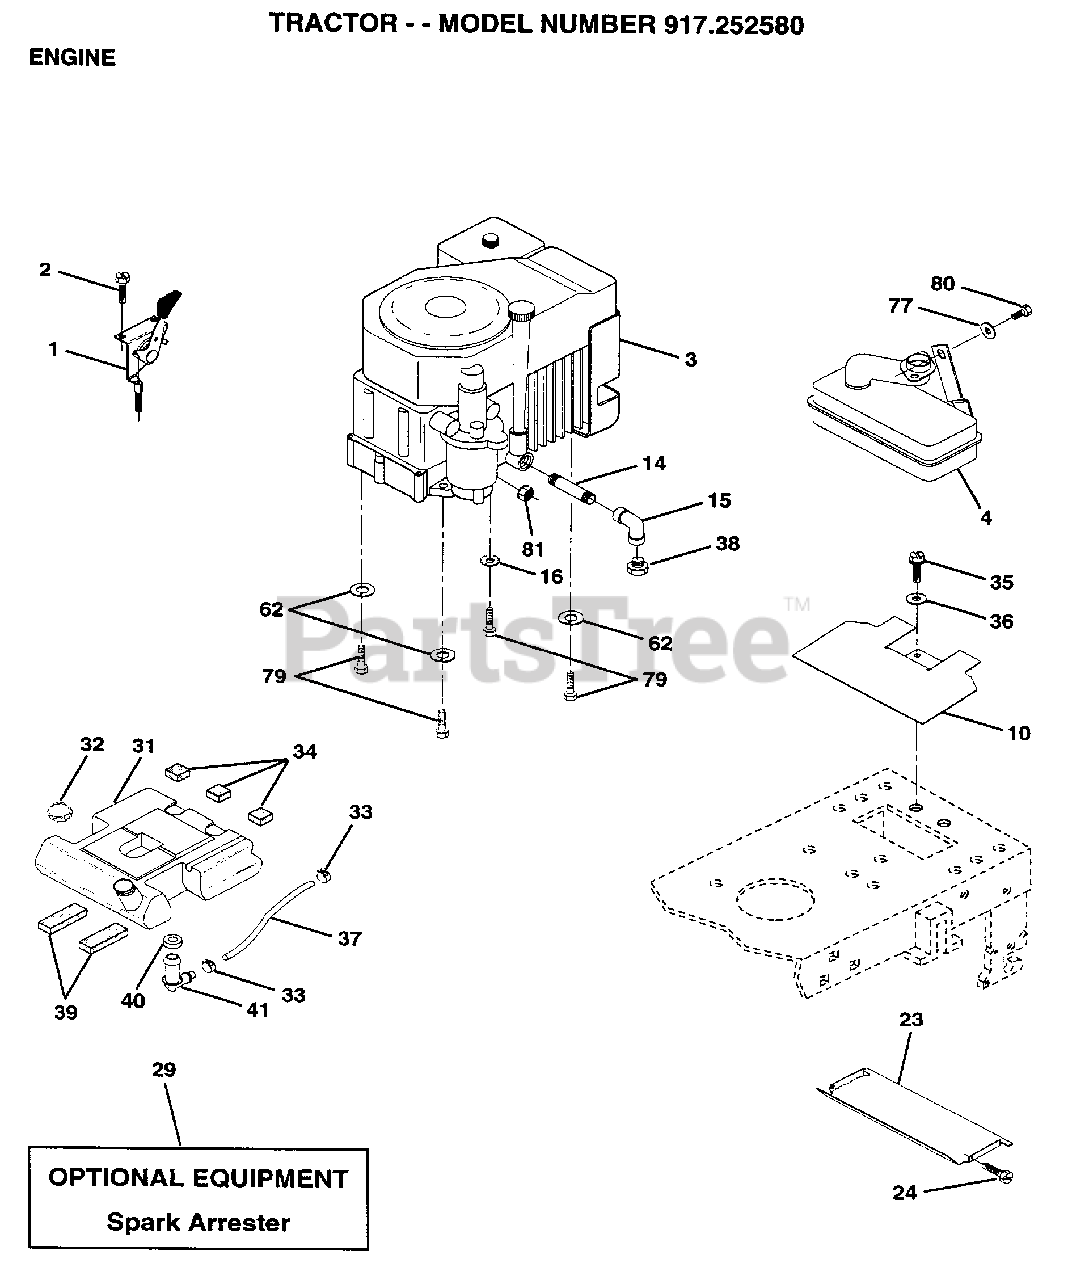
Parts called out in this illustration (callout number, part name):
2	SCREW LT
3	ENG KOHLER MODEL NO. CV15S PS41508
4	MUFFLER.LT.12.5
10	SHIELD.HEAT.
14	PIPE NIPPLE
15	ELBOW
23	HEAT SHIELD
33	HOSE CLAMP
34	PAD-SPACER LT
35	SCREW
36	WASHER
37	FUEL LINE T
39	PAD IDLER TI
40	BUSHING OUTLET T
41	STEM.TANK.FUEL
77	WASHER 5/16 X 3/4 X 16 GA.
81	NUT
